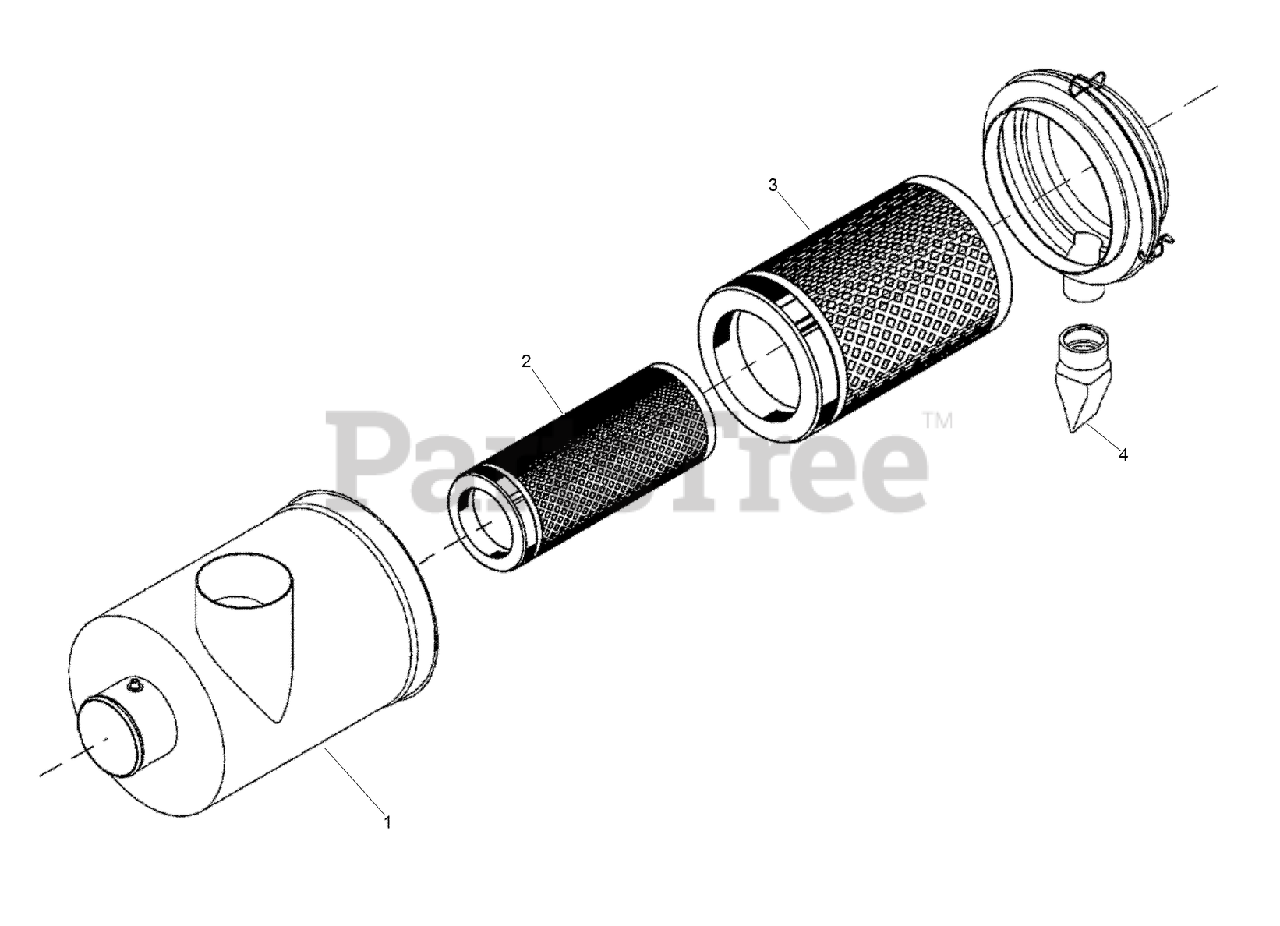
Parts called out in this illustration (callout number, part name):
1	ASM-Air Cleaner
2	ELEMENT - Filter, Primary
3	ELEMENT - Filter, Secondary
4	CAP - Dust Cover
